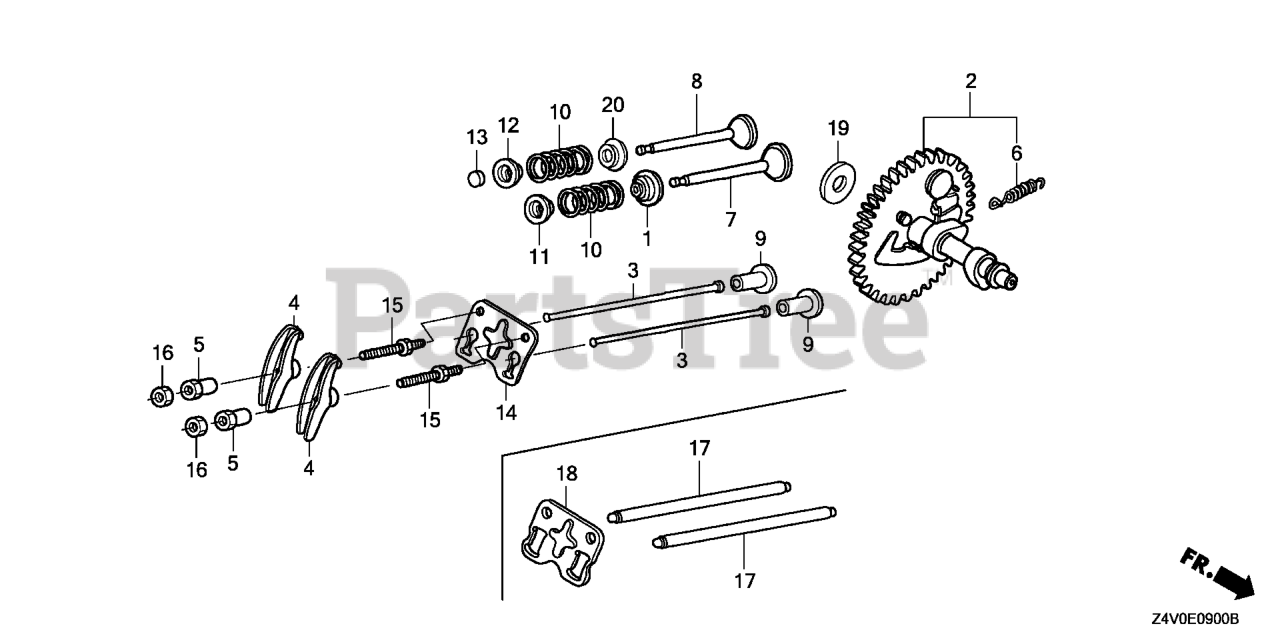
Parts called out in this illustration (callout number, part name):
1	SEAL, VALVE STEM
2	CAMSHAFT ASSY.
3	ROD, PUSH
4	ARM, VALVE ROCKER
5	PIVOT, ROCKER ARM
6	SPRING, WEIGHT RETURN
7	VALVE, IN.
8	VALVE, EX.
9	LIFTER, VALVE
10	SPRING, VALVE
11	RETAINER, VALVE SPRING (EXHAUST SIDE)
12	RETAINER, VALVE SPRING (EXHAUST SIDE)
14	PLATE, PUSH ROD GUIDE
15	BOLT, PIVOT (8MM)
16	NUT, PIVOT ADJ.
